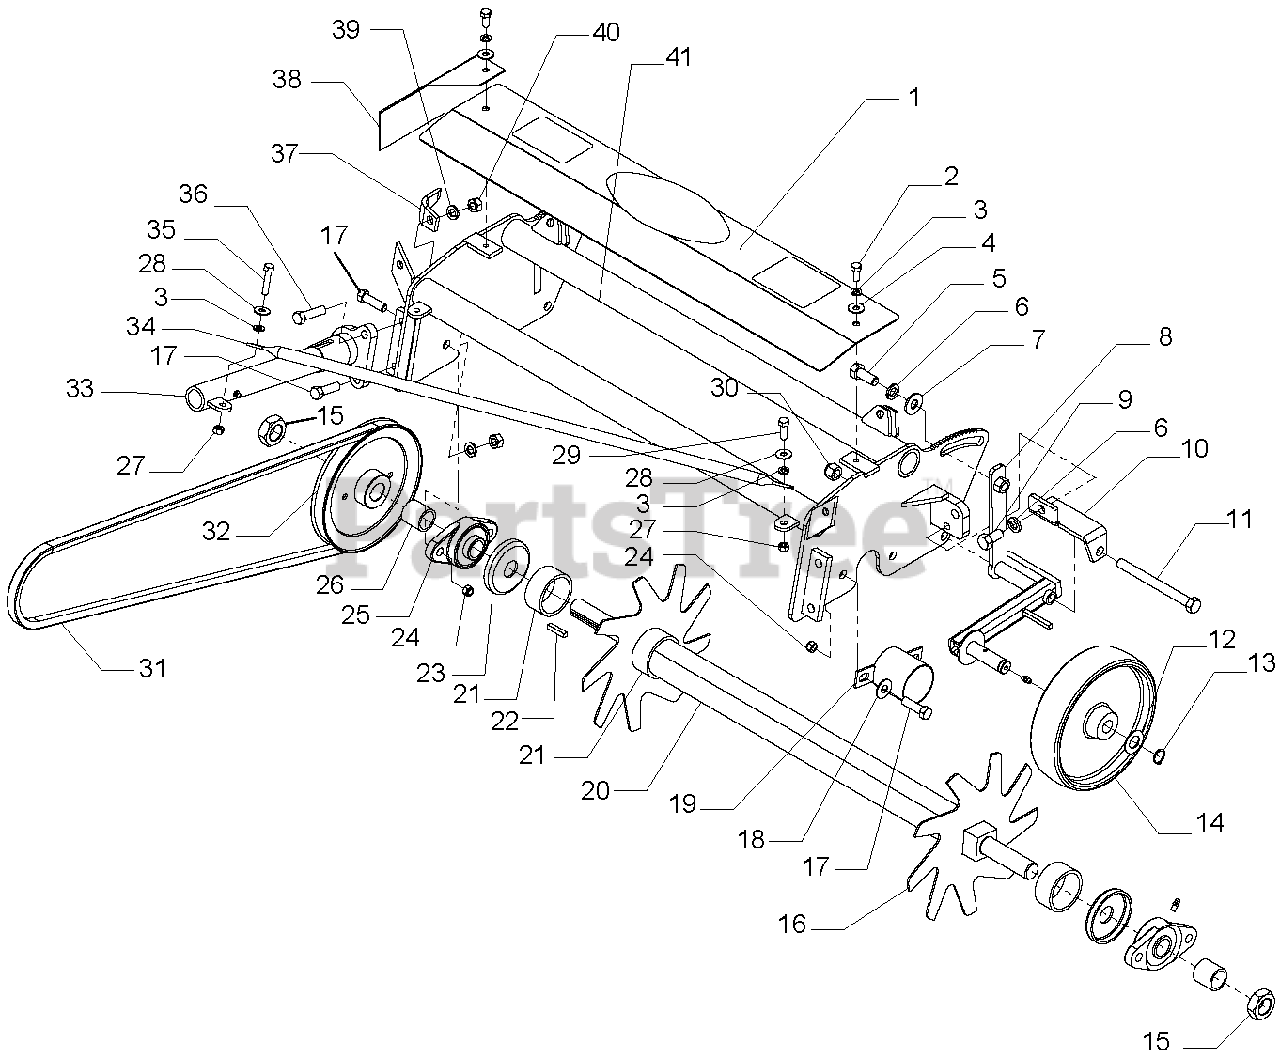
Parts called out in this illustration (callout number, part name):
1	Top Shield, #1, #2 & #3
2	Cap Screw, Hex Head 5/16-18 x 3/4
3	Washer, Lock 5/16 CP
4	Washer, Flat 5/16 USS CP
5	Cap Screw, Hex Head 1/2-13 x 1-1/4 CP
6	Washer, Lock 1/2 CP
7	Washer, Flat 1/2 SAE ZP
8	Wheel Pivot Arm Weldment, LH
9	Cap Screw, Hex Head 1/2-13 x 1
10	Wheel Brace, LH
11	Cap Screw, Hex Head 1/2-13 x 5-1/2 CP
12	Special Washer, Wheel
13	Snap Ring, External 3/4
14	Wheel, 8.00" OD x 2"
15	Jam nut, 1-14 NF
16	Dynablade, 9T 10" 12 Gauge
17	Cap Screw, Hex Head 7/16-14 x 1-1/2 C
18	Washer, Flat 7/16 SAE ZP
19	Shaft Shield Weldment
20	Blade Shaft
21	Spacer, Blade
22	Key, 1/4 x 1/4 x 1-1/4
23	Washer, Shaft
24	Nut, Hex 7/16-14 Nyloc CP
25	Bearing, 2 Bolt Flange
26	Spacer, Pulley
27	Nut, Hex 5/16-18 CP
28	Washer, Flat 5/16 SAE Hard YZ
29	Cap Screw, Hex Head 5/16-18 x 1
30	Nut, Hex 1/2-13 Nyloc CP
31	V-Belt, BX 68
32	Pulley, Verticutter Reel
33	Telescoping Arm
34	Stay Rod Stabilizer
35	Cap Screw, Hex Head 5/16-18 x 1-1/2
36	Cap Screw, Hex Head 7/16-14 x 1-3/4
37	Pulley Scraper, RH
38	Pulley Guard, RH
39	Lockwasher, 7/16 CP
40	Nut, Hex 7/16 CP
41	Frame Weldment, #1, #2 & #3
